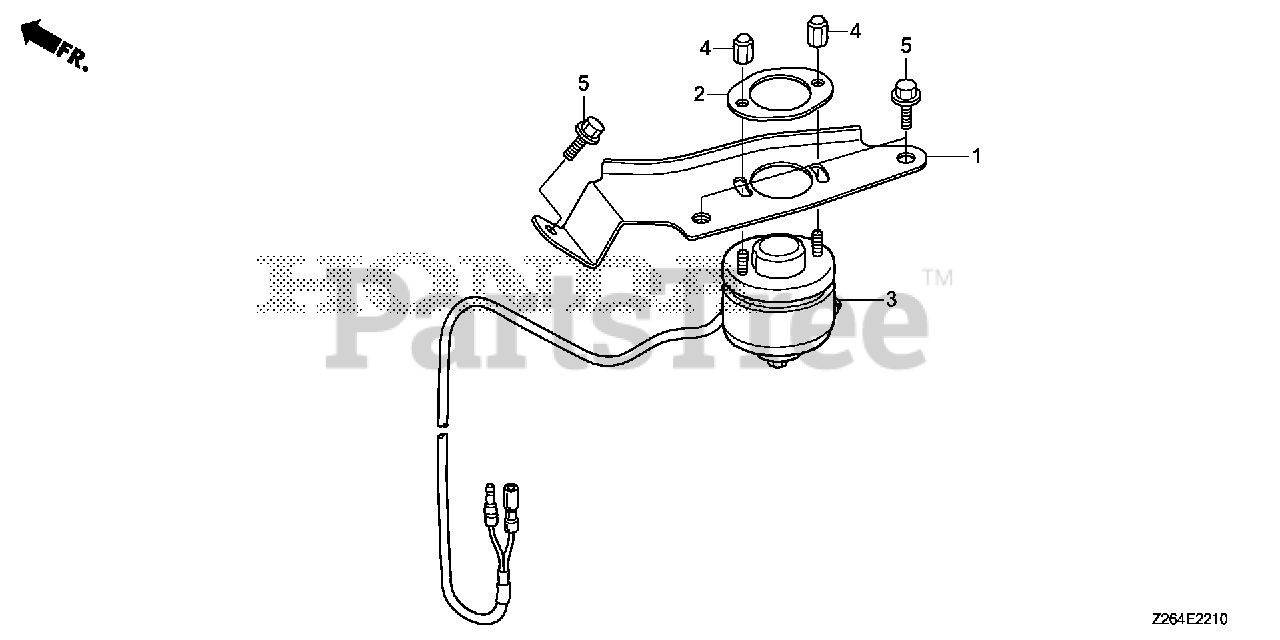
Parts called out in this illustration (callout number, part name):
1	STAY, SOLENOID
2	PLATE, SOLENOID
3	SOLENOID ASSY., ROTARY
4	NUT, SPECIAL CAP
5	BOLT, FLANGE (6X14)
